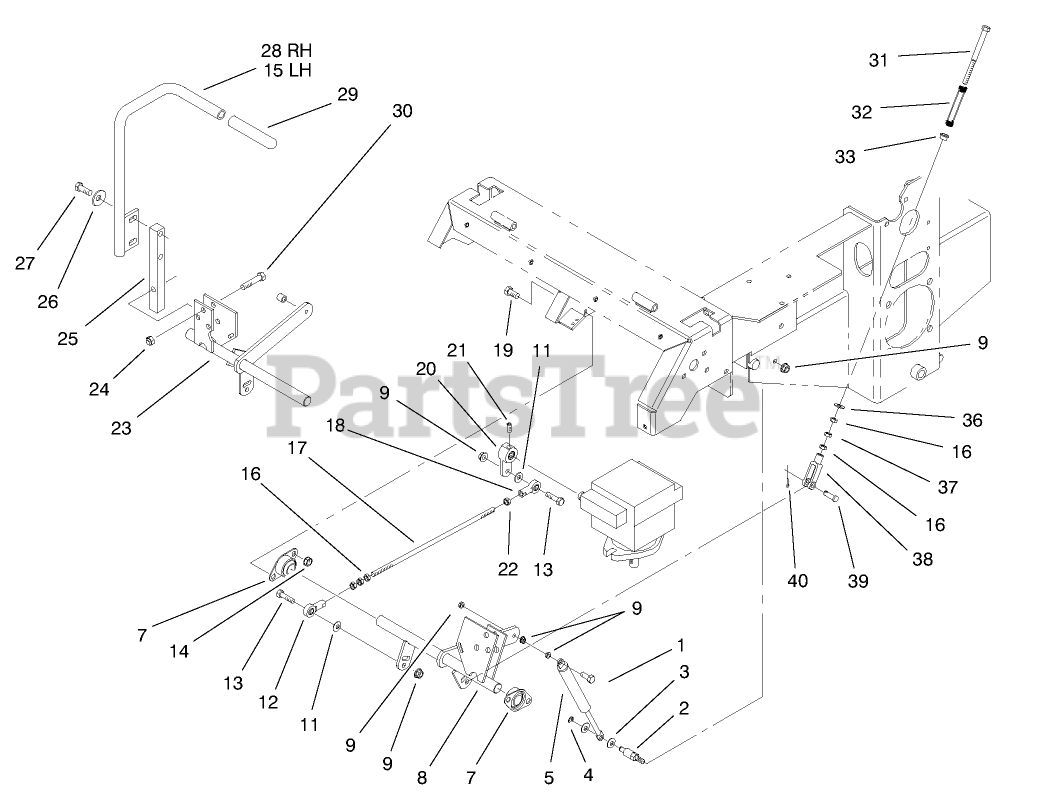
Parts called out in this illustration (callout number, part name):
1	SCREW-HH
2	Pin-Dampner
3	WASHER-PLAIN
4	E-Ring
5	Damper
7	Bearing-Side Flange
8	Motion Control, LH
9	NUT-HF
11	WASHER-FLAT
12	Ball Joint
13	SCREW-HH
14	NUT-HHF, WHIZ
15	Lever-LH
16	NUT-HEX
17	Link-Pump Control
18	Ball Joint LH
19	SCREW-HH
20	Arm-Pump Control
21	Screw
22	Nut
23	Motion Control, RH
24	NUT-LOCK, NI
25	Arm
26	Washer
27	SCREW-HH
28	Lever-RH
29	Grip
30	SCREW-HH
31	Bolt
32	Spring
33	Bushing
36	WASHER-FLAT
37	NUT-JAM
38	Yoke
39	Pin-Clevis
40	PIN-COTTER
